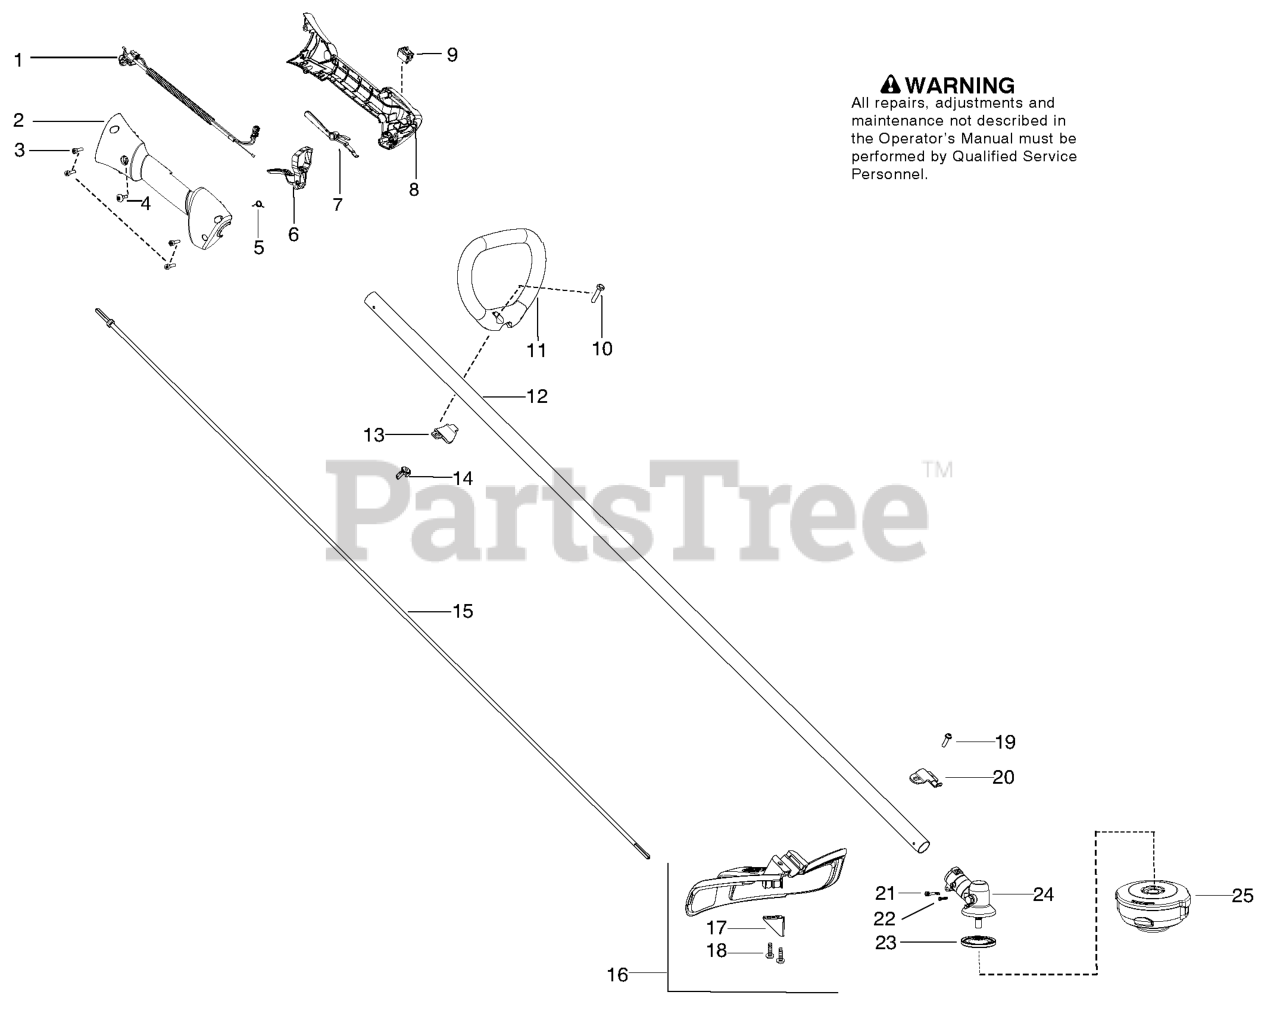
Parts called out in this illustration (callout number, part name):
1	Assy-Cable/Wire Harness
2	Housing-Throttle (RH)
3	Screw
4	Screw
5	SPRING TRIGGER
6	Trigger
7	Lockout-Throttle
8	Housing-Throttle (LH)
9	Kit-Switch
10	BOLT, TYPE 2
12	KIT DRIVE SHAFT SST US / CAN
13	CLAMP ASSIST HANDLE
14	WINGNUT, TYPE 2
15	FLEXSHAFT 57"
16	KIT COBI SHIELD
17	Limiter-Line
19	SCREW 1/4-20 X 7/8 (TAP
20	BRACKET SHIELD STRAIGHT SHAFT
21	SCREW - CARB. ADAPTOR
23	DRIVE DISC
24	ASSY GEARBOX
25	T25 TRIM HEAD 10MM LH
